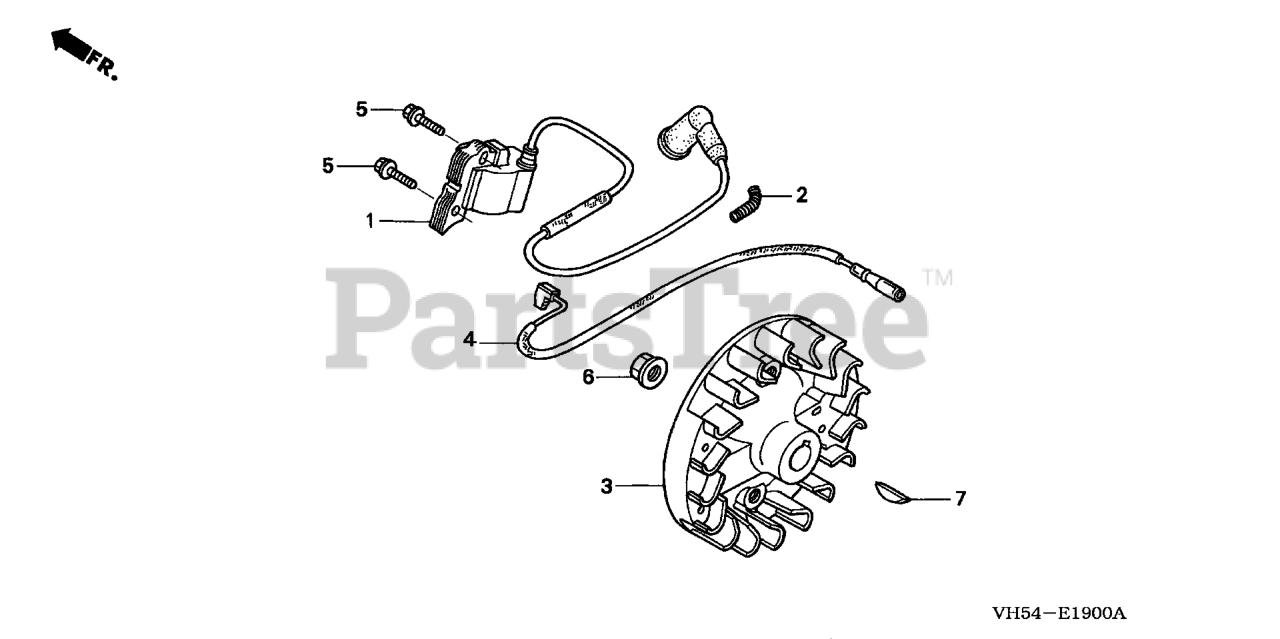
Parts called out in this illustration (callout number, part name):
1	COIL ASSY., IGNITION
2	TUBE A, CORRUGATED (7X18)
3	FLYWHEEL COMP.
4	WIRE, STOP SWITCH
5	BOLT-WASHER (5X16)
6	NUT, FLANGE (10MM)
7	KEY, WOODRUFF (16X12)
